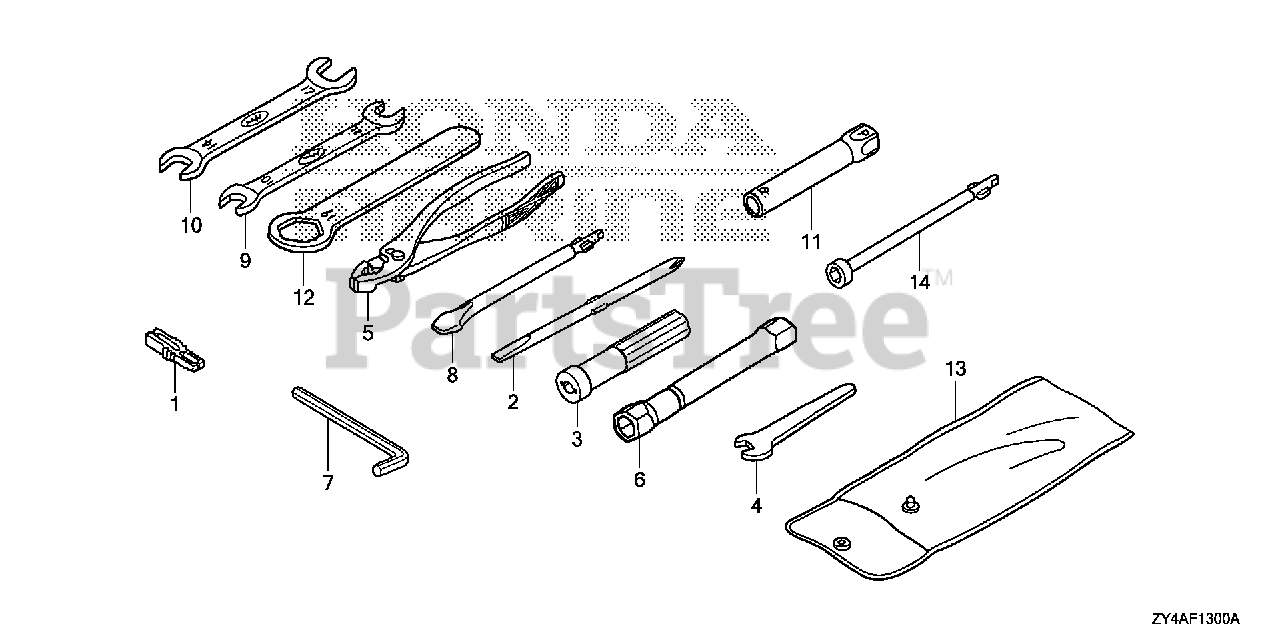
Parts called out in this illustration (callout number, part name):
3	GRIP, SCREW DRIVER
6	WRENCH, PLUG
7	WRENCH, HEX. (6MM)
8	DRIVER 3, MINUS SCREW (NO.2)
11	WRENCH, BOX (10MM)
12	WRENCH, EYE (19MM)
